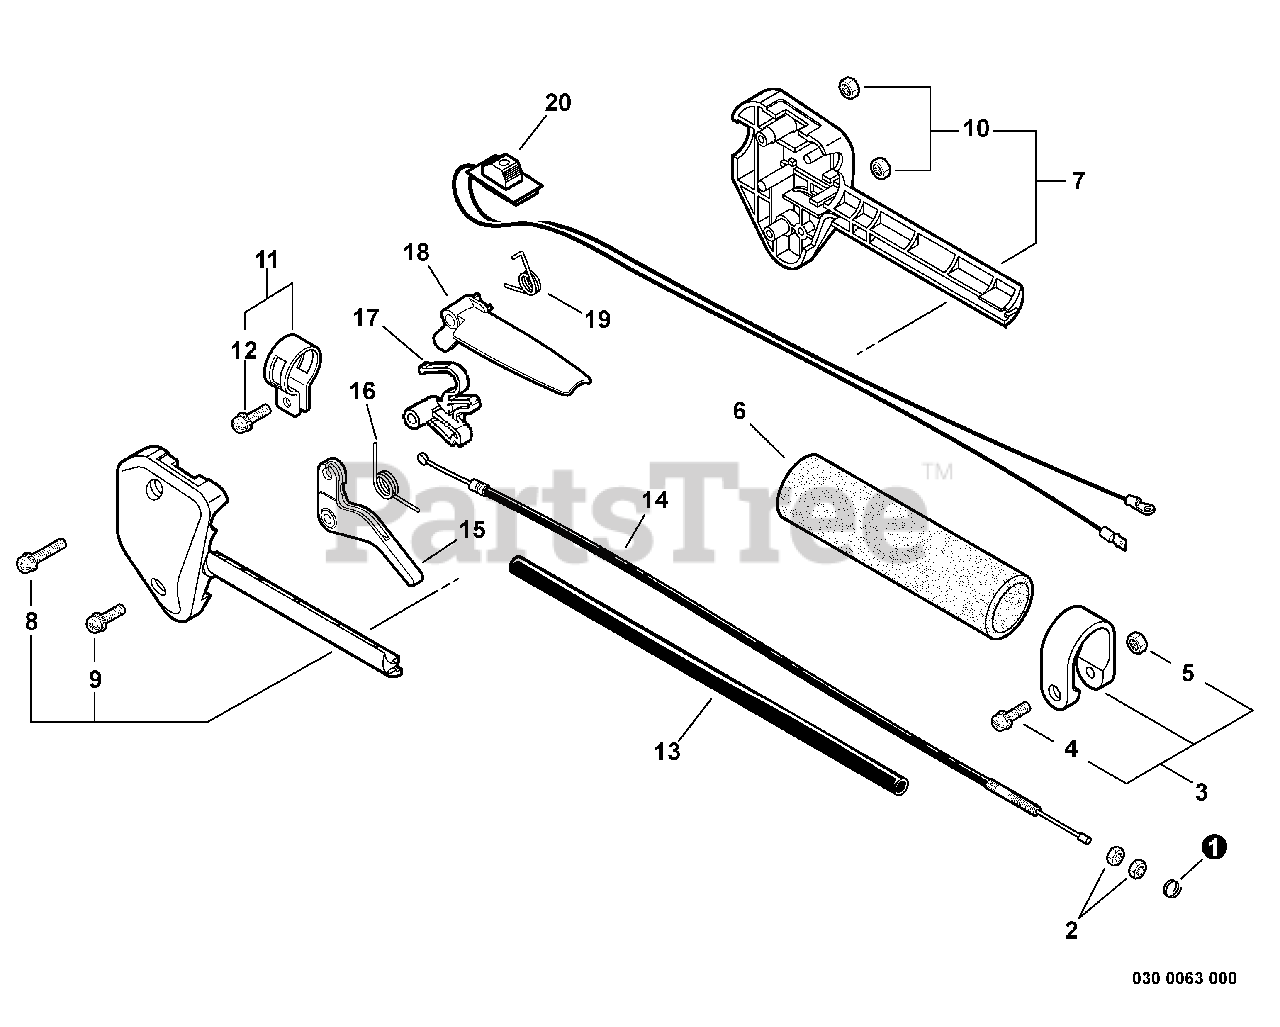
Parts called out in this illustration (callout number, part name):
3	CLAMP KIT
4	SCREW - 5X28
6	GRIP, HANDLE
7	CONTROL HANDLE KIT
8	SCREW - 5X35
9	SCREW - 5X25
11	CLAMP KIT
12	SCREW - 5X14
13	TUBE, PROTECTIVE
14	CABLE, THROTTLE
15	TRIGGER, THROTTLE
16	SPRING, TRIGGER
17	LOCKOUT, THROTTLE
18	LEVER, TRIGGER LOCKOUT
19	SPRING, LOCKOUT LEVER
20	IGNITION SWITCH ASSY
